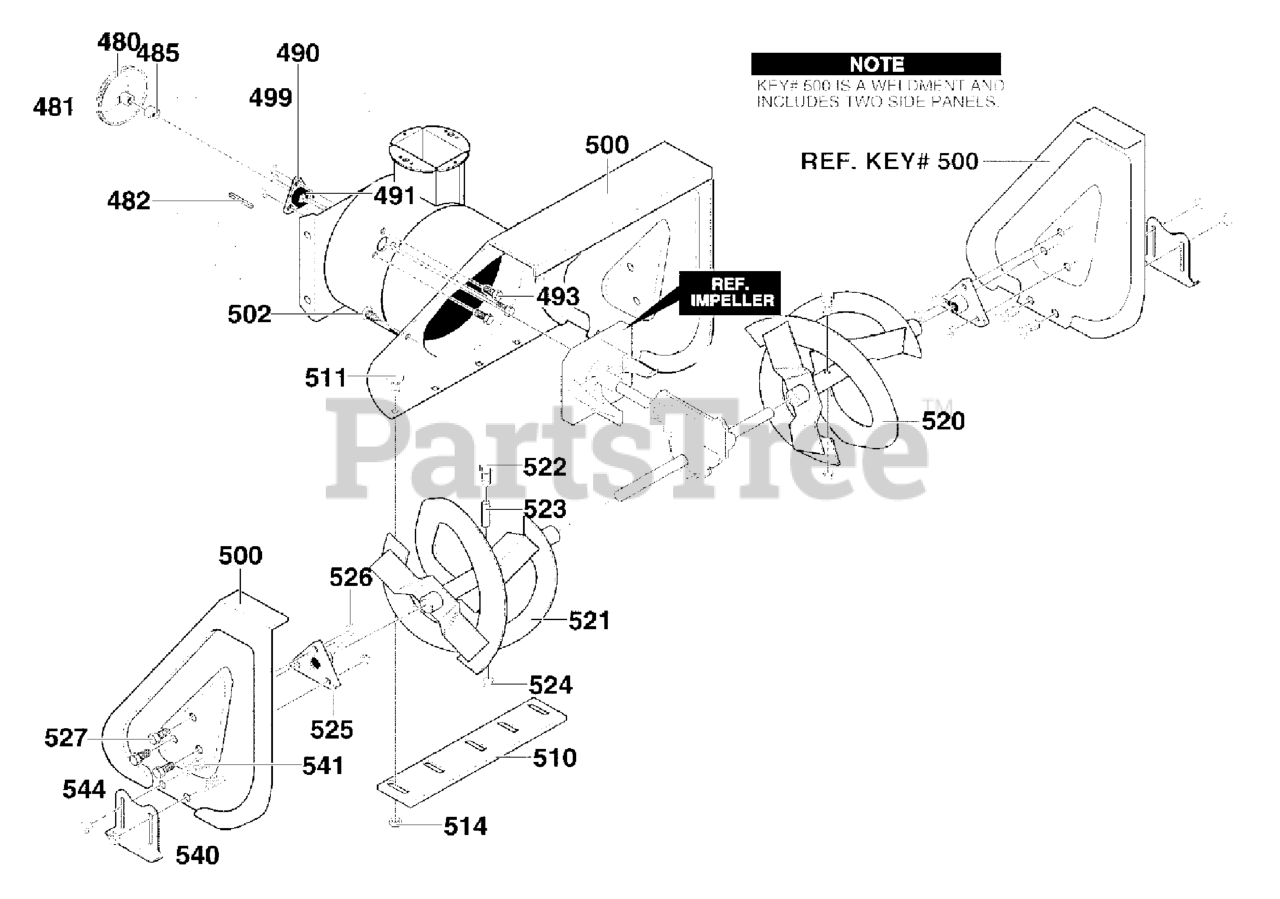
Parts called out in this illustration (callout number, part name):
481	SCREW, 5/16-18 x 0.63
482	KEY, SQUARE
485	SPACER, SLEEVE
490	RETAINER, BALL BRNG
491	BEARING, BALL
493	SCREW, 5/16-18 x 0.75
499	NUT, 5/16-18 HEX
500	HOUSING, ASSY
502	FASTENER, RATCHET
510	BLADE, SCRAPER 24"
511	BOLT, 1/4-20X.75
514	NUT, 1/4-20
520	AUGER, ASSY, LH
521	AUGER, ASSY, RH
522	SCREW, 1/4-20X1.75
523	SPACER, SLEEVE
524	NUT, 1/4-20
525	BEARING, FLANGE
526	NUT, 5/16-18
527	SCREW, 5/16-18 x 0.75
540	SKID, HEIGHT ADJUST
541	BOLT, 5/16-18 X .75
544	NUT, 5/16-18 HEX
